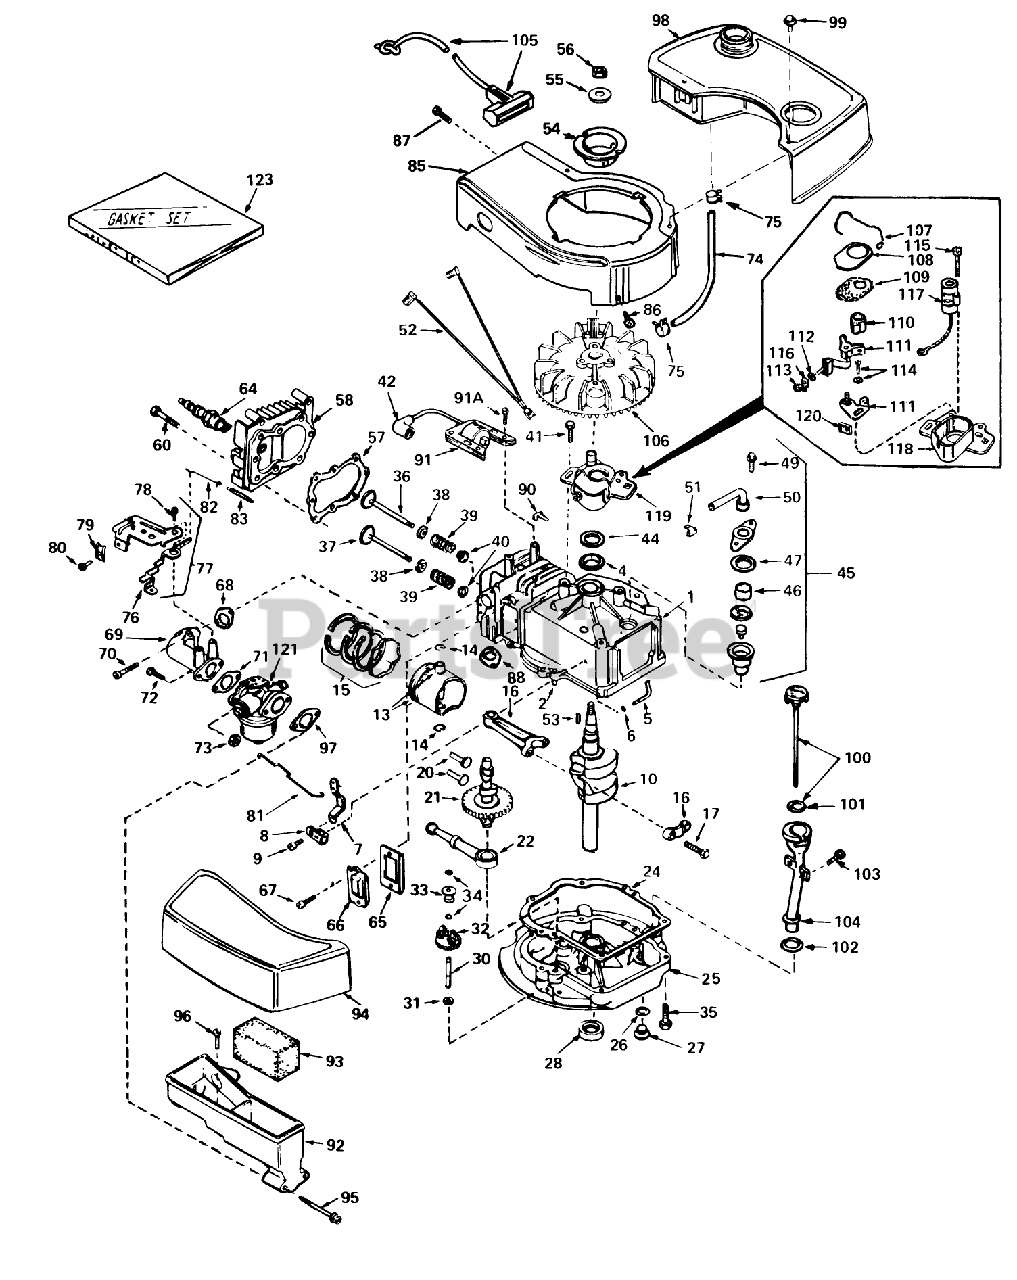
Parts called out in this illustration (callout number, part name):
1	Cyiinder Assy. (Incl. Ref. #2, 4 105)
2	Pin-Dowel
4	Seal-Oil
5	Rod, Governor (Incl. No. 36)
6	Washer-Flat
7	Governor Lever
8	Clamp-Lever, Governor
9	Screw
10	Crankshaft
13	Piston, Pin Ring Assy. (Incl.Ref. #14 15)(Std.)
13	Piston, Pin Ring Assy. (Incl. #14 15)(.010 oversize)
13	Piston, Pin Ring Assy. (Incl.Ref. #14 15) (.020 oversize)
14	Ring-Retaining, Piston Pin
15	Ring Set Piston (Std.)
15	Ring Set Piston (.010 Oversize)
15	Ring Set Piston (.020 Oversize)
16	Rod Assy., Connecting (Incl. Ref. #17)
17	Bolt-Rod, Connecting
20	Lifter-Valve
21	Camshaft(Mech.Comp. Release)
22	Oil Pump ASM
24	Gasket, Mounting
25	Flange Assy., Mounting (Incl. Ref. #26thru 30)
26	Gasket-Oil Drain
27	Plug Oil Drain
28	Seal Oil
30	Shaft-Governor
31	Washer-Flat
32	Governor Gear ASM
33	Spool-Governor
34	Ring-Retaining
35	Screw (1/4-20 x 1-1/4)
36	Valve, Intake (Incl. Ref. #38, 39 40) (Std.)
36	Valve, Exhaust (1/32" Oversize) (Incl. Nos. 8, 9 10)
37	Valve, Exhaust (Standard) (Incl. Nos. 8, 9 10)
37	Valve, Exhaust (1/32" Oversize) (Incl. Nos. 8, 9 10)
38	Cap-Upper Valve Spring
39	Spring-Valve
40	Cap-Valve, Spring
41	Screw
42	Cover-Spark Plug
44	Gasket Stator
45	Breather Assy. (Incl. Ref. #46, 47, 49, 50 51 )
46	Element-Breather
47	Gasket-Breather
49	Screw, Hex Hd. w/Conical
50	Tube, Breaker
51	Clip, Breather
52	Wire Ground
53	682488 LB GRASS HI-
54	Hub-Starter
55	Washer-Belleville
56	Nut-Flywheel
57	63573 GIL 42 SNWTHW
58	Head-Cylinder
60	Screw
64	Plug, Spark (J17LM or equiv.)
64	Plug, Spark (Champion RCJ-8)
65	Gasket-Breather
66	Cover-Valve
67	Screw
68	Gasket, Intake
69	Pipe, Intake
70	Screw (1/4-20 x 1)
71	Gasket-Carburetor
73	Nut and Lock Washer (1/4-28)
74	Line-Fuel
75	Clamp-Line, Fuel
76	Lever Control
77	Control Assy., Speed (Incl. Nos, 76, 78 89)
78	Screw, Hex Washer Hd Shoulder Self-Tap
79	Conduit
80	Screw (10-32 x 3/8)
81	Link-Throttle
82	Link Governor Spring
83	Spring Governor
85	Housing Blower
86	Screw
87	Screw (10-24 x 9/16)
88	Gasket Exhaust
90	Clip-Wire
91	Lamination Coil Assy. (Incl. No. 42)
91A	Screw
92	Body Air Cleaner
93	Filer, Air
94	Cove, Air Cleaner
95	Screw Fil Hd.
96	Screw, Hex Hd.
97	Gasket-Air Cleaner
98	Tank, Fuel
99	Screw (10-32 x 35/64)
100	Dipstick, Oil (Incl. Ref. #101)(Twist Lock)
101	O-Ring
102	Gasket
103	Screw (10-32 x 1/2)
104	Tube-Oil Fill
105	Rope Assy., Starter
106	FIywheel
107	Spring Breaker Box
108	Cover-Dust
109	Gasket-Dust Cover
110	Cam-Breaker
111	Breaker Assy.
112	Washer
113	DECAL
114	Breaker Screw
115	Condenser Screw
116	Terminal, Ground
117	Condenser
118	Stator Plate
119	Stator Plate Assy. (incl. Nos. 107, 111 thru 118 120)
120	Felt, Cam Wiper
121	Carburetor (Incl. Ref. #71 )
123	53024/VAR.16HP O/P
